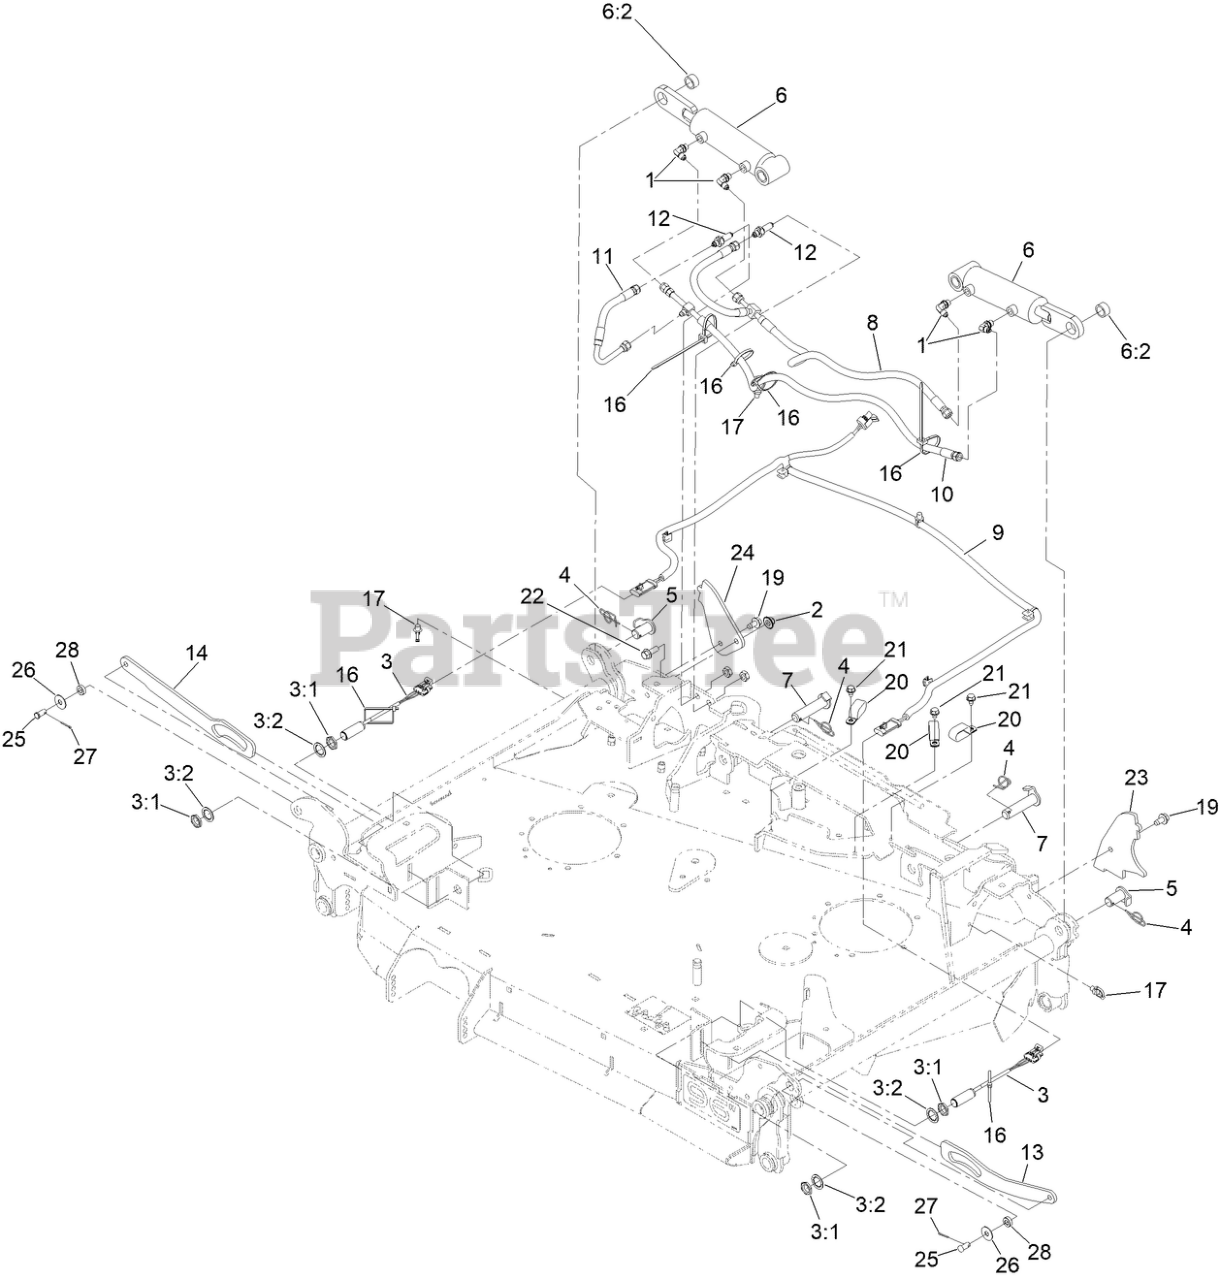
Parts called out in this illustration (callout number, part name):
1	Adapter, 90?
2	NUT-FLANGE, NI
3	PROXIMITY SWITCH ASM
3:1	NUT-HEX
3:2	WASHER-LOCK, INTERNAL TOOTH
4	PIN-LOCKING COTTER
5	PIN-CYLINDER
6	CYL-DECK FOLD
6:2	BUSHING-0.75X1.00X0.50 LONG
7	ASM-CYL PIN BASE
8	HOSE ASM
9	HARNESS-WIRE
10	HOSE ASM
11	HOSE ASM
12	FITING-STRAIGHT
13	STRAP- LH FLAG
14	STRAP-RH FLAG
16	TIE-CABLE
17	CLIP-TIE
19	SCREW-HWH
21	SCREW
22	SCREW-HHF
23	BRACKET-DECK STOP, LH
24	BRACKET-DECK STOP, RH
25	PIN-CLEVIS
26	WASHER
27	PIN-COTTER
28	BUSHING
